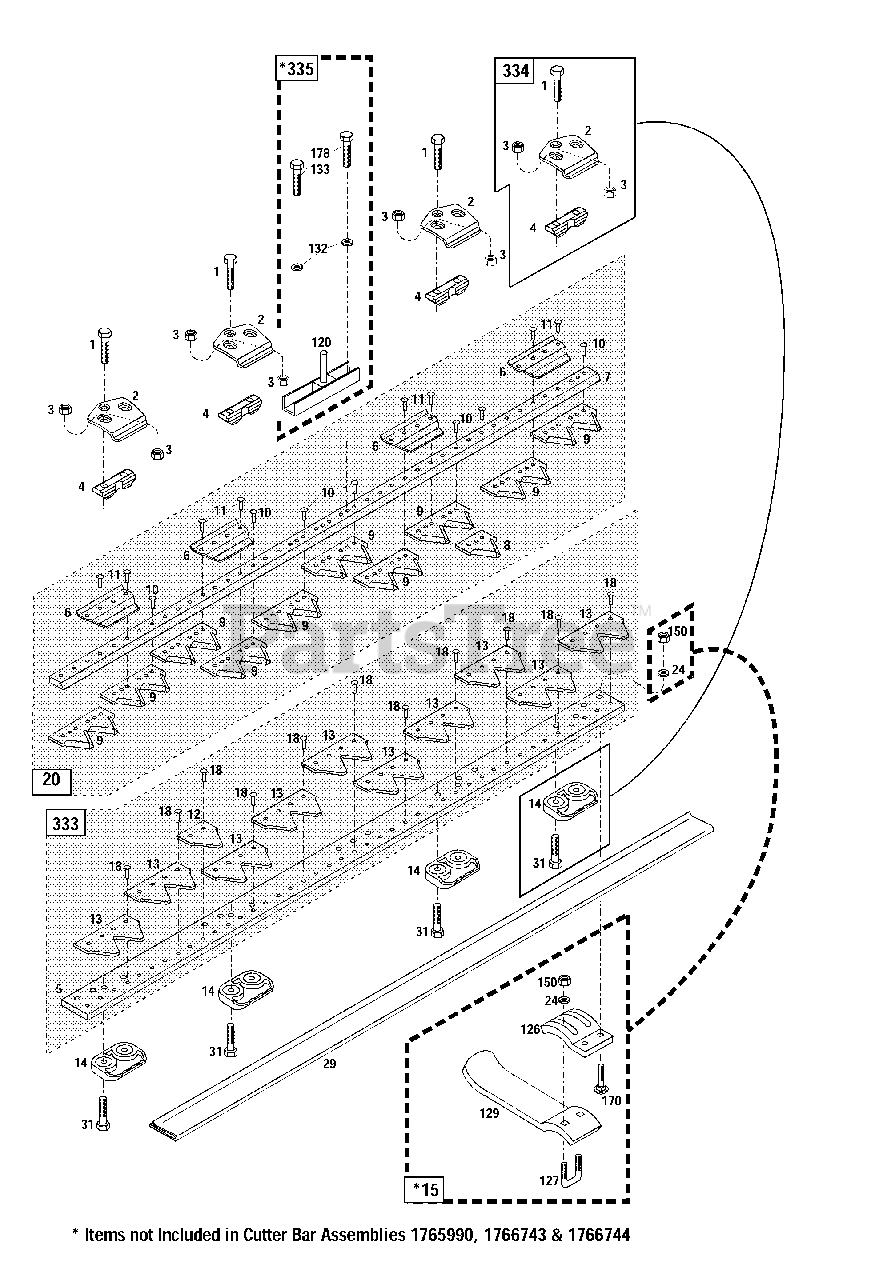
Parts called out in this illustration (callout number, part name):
1	Hex Head Screw, M8 x 0.30
2	Hold-Down Clip
3	Lock Nut, M8
4	Knife Guide
5	34" Ledger Plate Bar
6	Wear Plate
7	34" Blade Knife Bar
8	Blade (single)
9	Blade (double) 34"
10	Rivet Section, 5 x 17 (pack of 12)
11	Rivet Section, 5 x 20 (pack of 12)
12	Ledger Plate (single)
13	Ledger Plate (double)
15	Skid Assembly
18	Ledger Rivet, 6 x 20 (pack of 12)
20	34" Blade Assembly
24	Flat Washer, 5/16
29	Blade Guard, 34"
31	Hex Head Screw, M8 x 45
120	Knife Head
126	Shoe Holder
127	U-Bolt, 5/16
132	Flat Washer (hardened), 5/16
133	Hex Head Capscrew, M8 x 12
150	Nylock Nut, 5/16-18
170	Carriage Bolt, 5/16-18 x 1, Grade 5
178	Loctite (R) Thread Compound
333	34" Ledger Plate Assembly
334	Hold-Down Clip Kit
335	Knife Head & Pitman Kit
